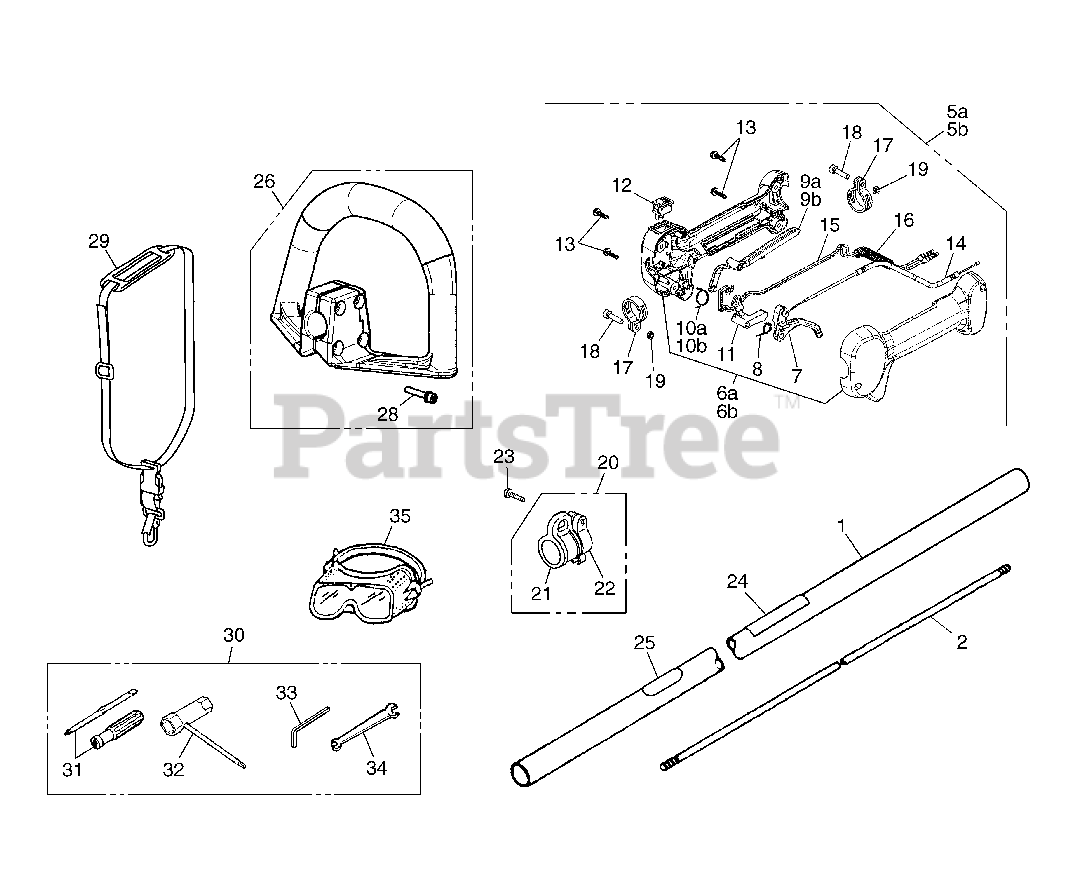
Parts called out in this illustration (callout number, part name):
1	PIPE-C
5	GRIP ASSY
6	GRIP HALF SET
7	LEVER, THROTTLE
8	SPRING, THROTTLE
9	LEVER FOR GRIP (RPLS -0600)
9	LEVER, SAFETY
10	SPRING JOINT
10	SPRING
11	LEVER JOINT
15	CORD - C
19	NUT
20	HANGER COMP.
21	HANGER
25	Caution Label
26	HANDLE ASSY. (RPLS T319514001)
29	STRAP ASSY
30	TOOL-SET
35	GOGGLExxx (RPLS
